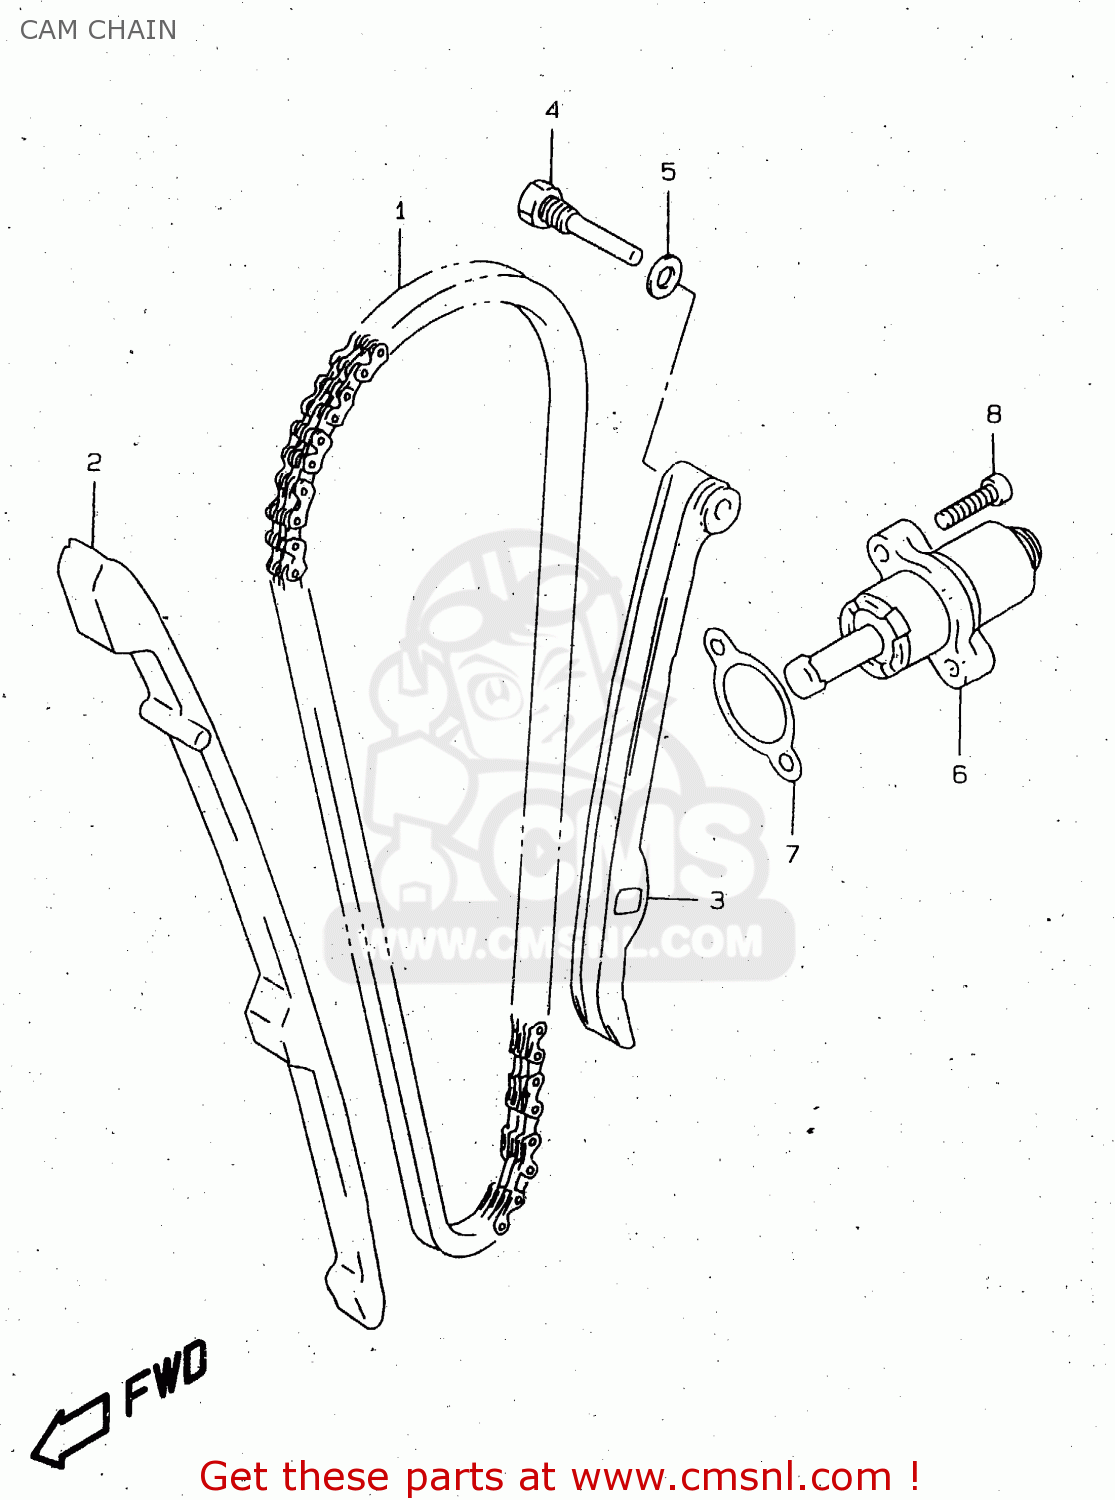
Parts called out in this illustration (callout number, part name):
1	CHAIN,CAMSHAFT DRIVE
2	GUIDE,CAM CHAIN
3	TENSIONER,CAM CHAIN
4	BOLT,CAM CHAIN TENSIONER
5	GASKET 8.2X14X1 (NAS)
6	ADJUSTER ASSY,TENSIONER
7	GASKET,TENSIONER ADJUSTER (NAS)
8	BOLT,CL.COVER
